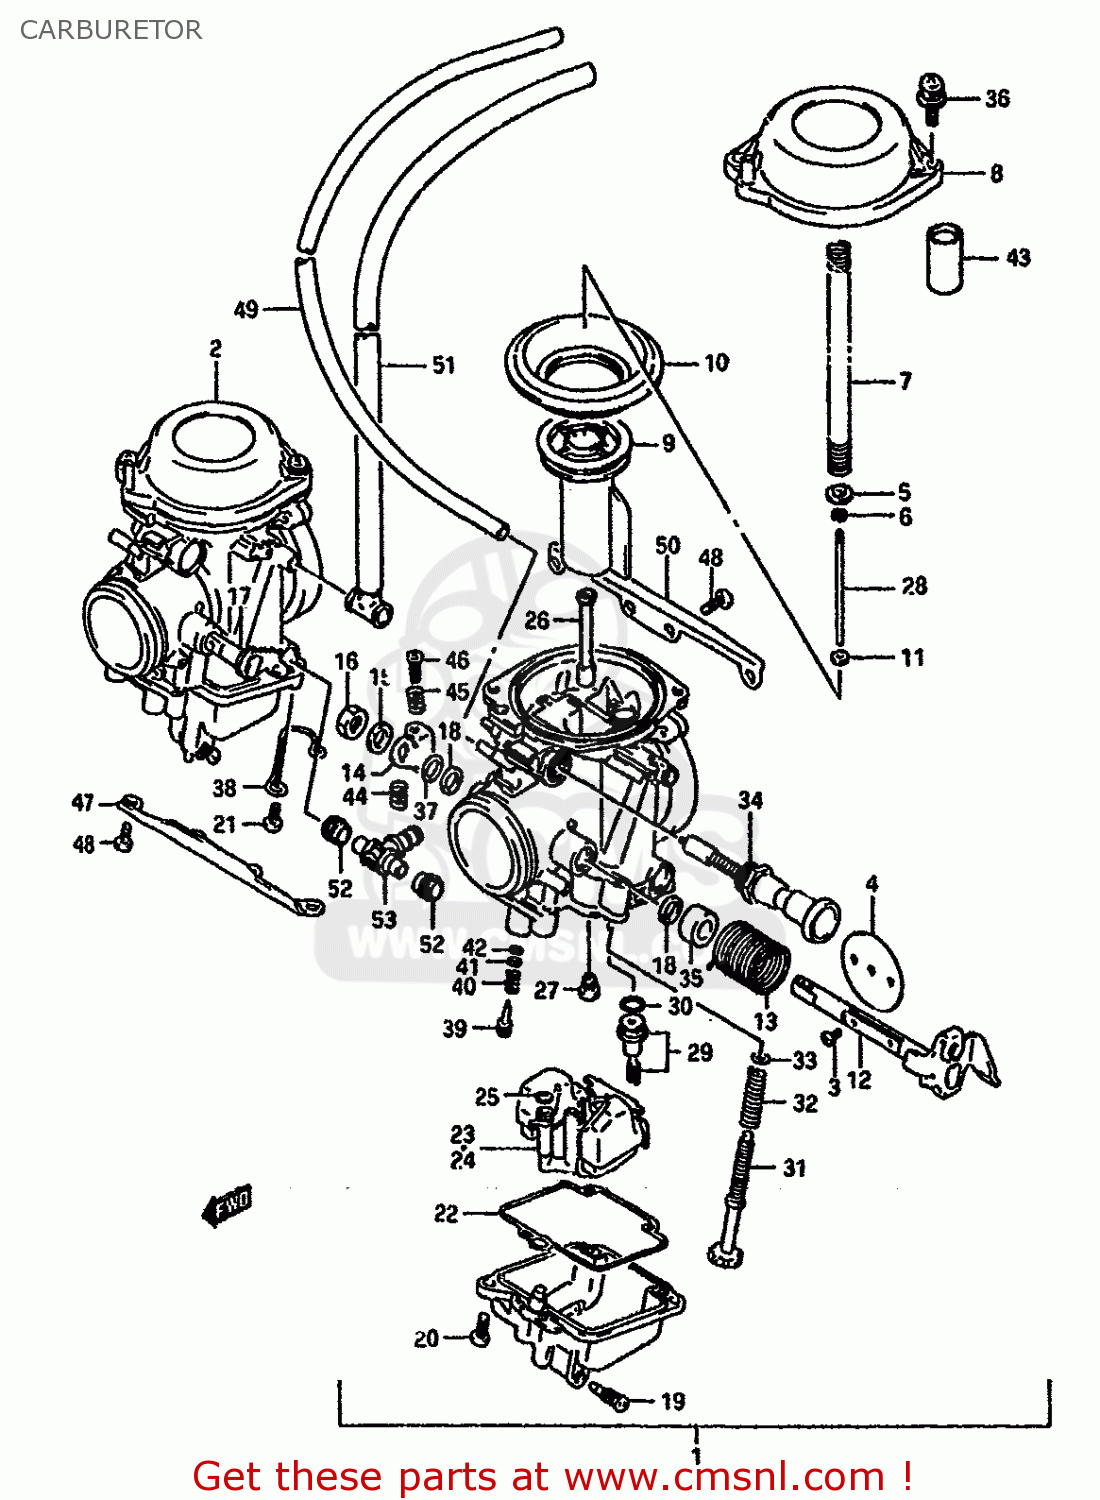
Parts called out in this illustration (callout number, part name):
1	CARBURETOR ASSY,LH
2	CARBURETOR ASSY,RH
3	SCREW
4	VALVE,THROTTLE (100)
5	RING
6	CLIP
7	SPRING
8	COVER,DIAPHRAGM
9	VALVE PISTON
10	DIAPHRAGM
11	RING
12	SHAFT ASSY
13	SPRING
14	LEVER,THROTTLE
15	WASHER,LOCK,8.
16	NUT
17	SHAFT ASSEMBLY
18	SEAL
19	PLUG,DRAIN
20	SCREW 5X12
21	SCREW
22	GASKET,FLOAT CHAMBER (NAS)
23	FLOAT ASSY
24	FLOAT ASSY
25	O RING
26	JET,NEEDLE(O-4)
27	JET,MAIN(120)
28	NEEDLE,JET
29	VALVE ASSEMBLY,NEEDLE
30	O-RING,NEEDLE VALVE
31	SCREW
32	SPRING
33	WASHER
34	PLUNGER ASSY
35	RING
36	SCREW
37	GASKET,THROTTLE SHAFT (NAS)
38	CLIP
39	SCREW,PILOT
40	SPRING
41	WASHER
42	O RING,PILOT AIR SCREW
43	RING
44	SPRING,THROTTLE SCREW
45	SPRING
46	SCREW
47	PLATE
48	SCREW 5X12
49	HOSE
50	PLATE
51	HOSE
52	SEAL
53	NIPPLE
